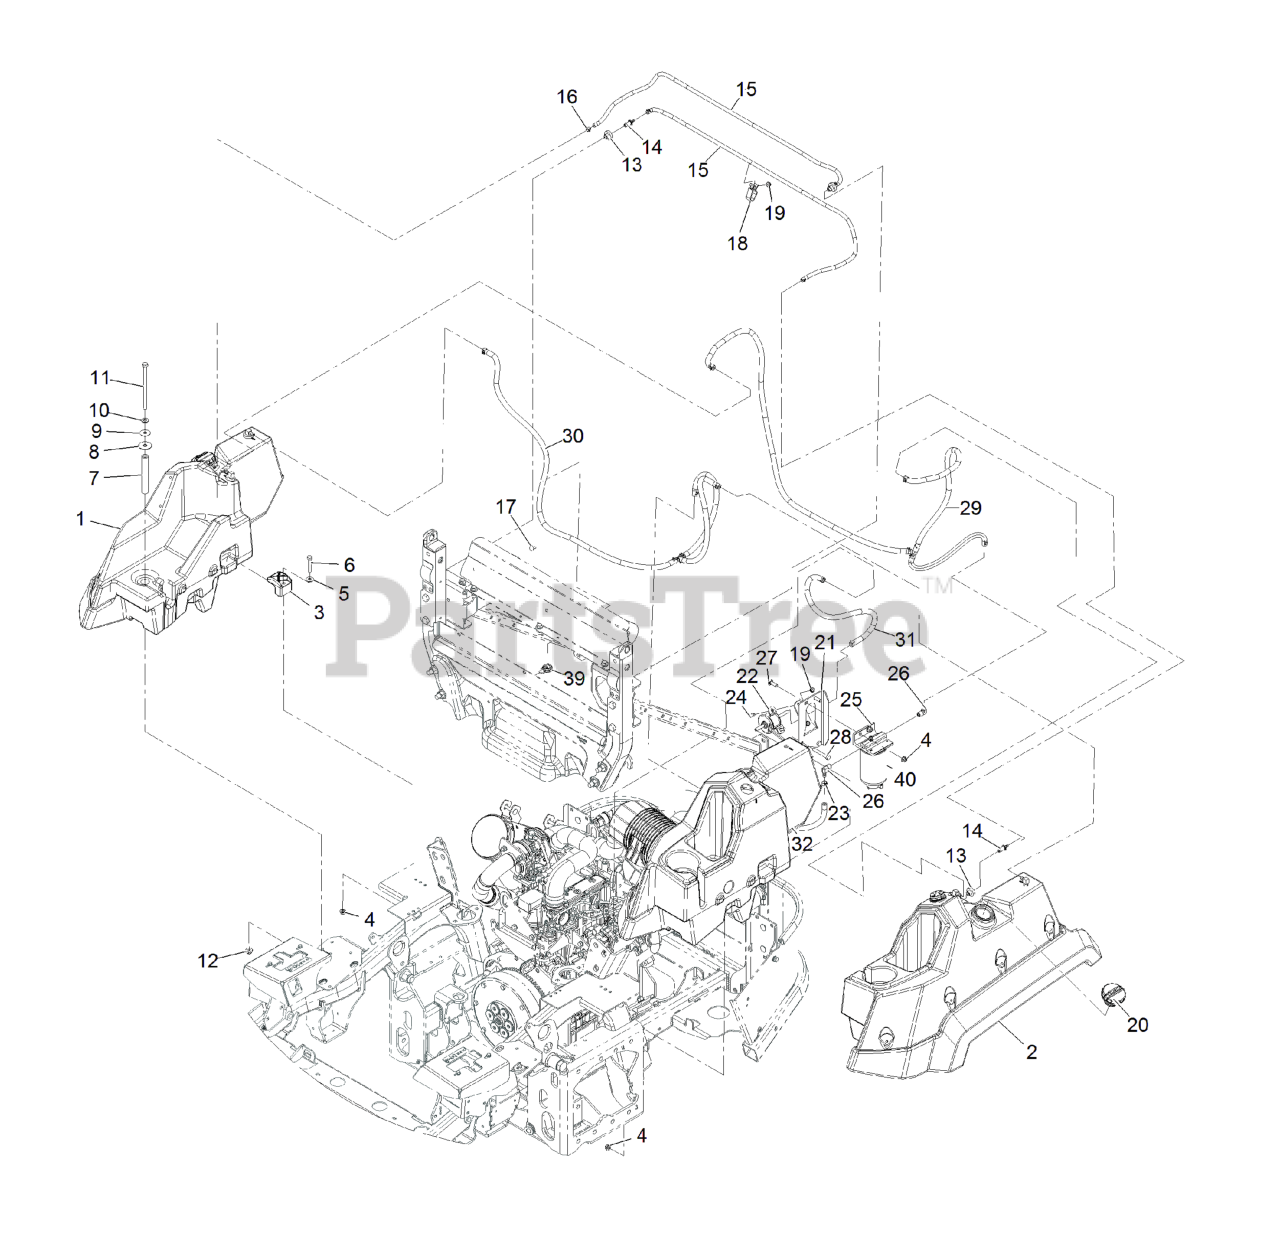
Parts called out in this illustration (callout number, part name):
1	RH FUEL TANK ASM
2	LH FUEL TANK ASM
4	NUT-HF, NI
5	WASHER-FLAT
6	SCREW-HH
7	TUBE-SPACER
8	WASHER-RUBBER
9	WASHER-PLAIN
10	WASHER-FLAT
11	SCREW-HH
12	NUT-HF, NI
13	BUSHING
14	FITTING-ORIFICE, STRAIGHT
15	HOSE-VENT, TANK
16	CLAMP-HOSE
17	SCREW-CARR
18	CLAMP-HOSE
20	CAP-FUEL, DIESEL
21	BRACKET-FILTER AND PUMP,
22	PUMP-FUEL, ELECTRIC
23	CLAMP-HOSE
24	SCREW-HWH
25	ASM,Fuel Filter W/Head
26	FITTING-HYD, 90
27	SCREW-CARR
28	SCREW-HH
29	LINE-FUEL, SUCTION
30	LINE-FUEL, RETURN
31	HOSE-FUEL
32	HOSE-FUEL
39	CLIP-TIE
40	FILTER-FUEL
